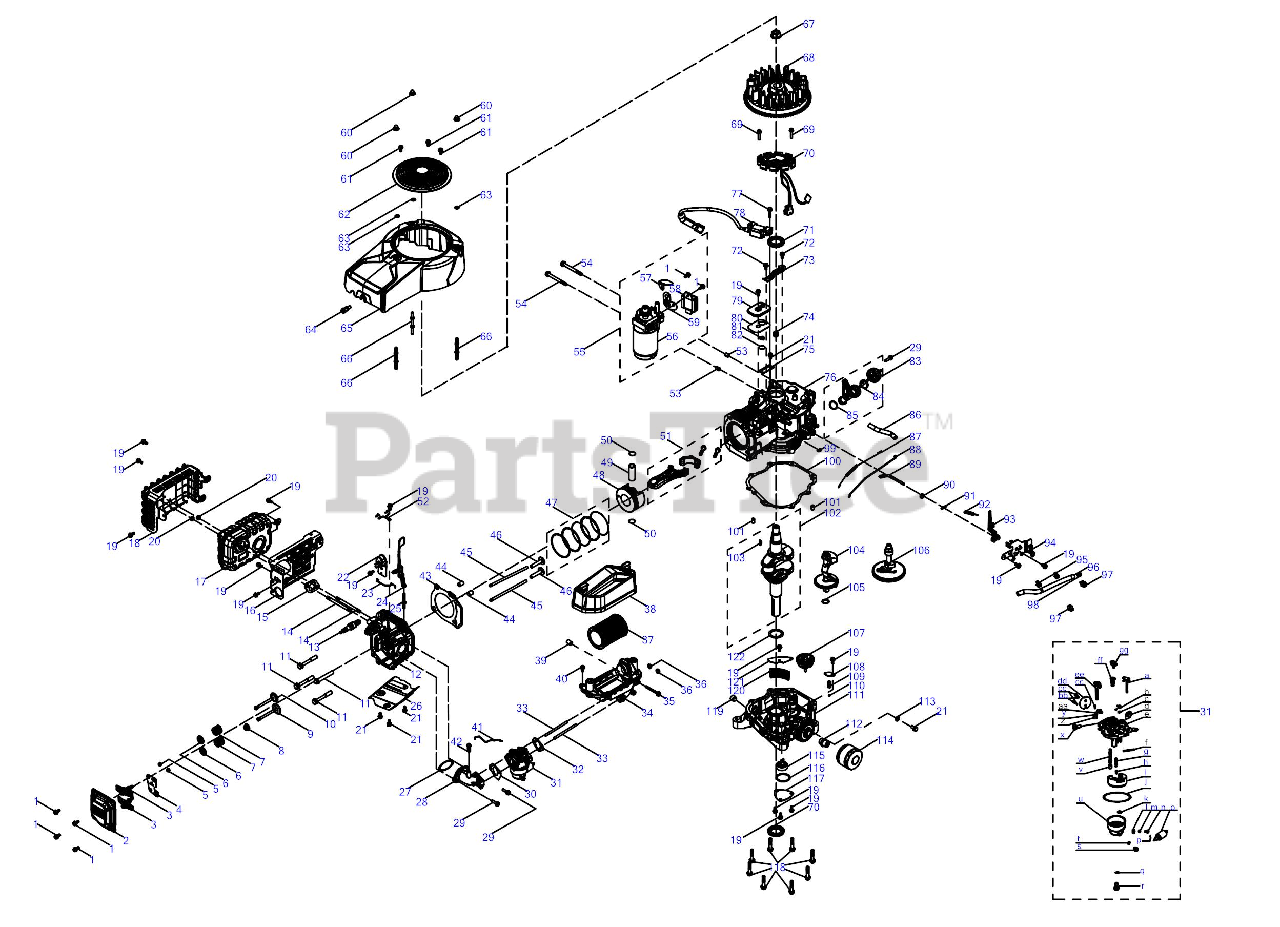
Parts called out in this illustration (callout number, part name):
1	Bolt, M6X16
2	Valve Cover
3	Rocker Arm Assembly
4	Rocker Arm Base
5	Valve Adjust Cap, Exhaust
6	Valve Spring Seat
7	Valve Spring
8	Intake Valve Seal
9	Intake Vavle
10	Exhaust Valve
11	Bolt, M10X1.25X70
12	Cylinder Head
13	Spark Plug
14	Stud, M8X102
15	Gasket, Muffler
18	Muffler Guard
19	Bolt, M6X14
21	Bolt, M6X12
22	Thermal Switch
23	Thermal Lever
24	Shield Assembly
26	Shroud, Down
27	O-Ring,36X2.5
28	Inlet Pipe
29	Bolt, M6X22
30	Gasket, Carburetor
31	Carburetor
32	Gasket, Air Filter
33	Stud, M6X92
34	Air Filter Base Assembly
35	Bolt, M6X55
37	Air Filter Element
38	Air Filter Cover Assembly
39	Bush, 11X6.6X30
40	Bolt, M6X18
41	Choke Lever
42	Self-tappling Screw, ST4.8X16
43	Gasket, Cylinder Head
44	Pin, 12X16
46	Tappet
47	Piston Ring Set
49	Piston Pin
50	Circlip
51	Connecting Rod Assembly
54	Bolt, M8X80
55	Electric Starter
56	Electric Starter
57	Flywheel Outlet Shield
60	Nut, M6
61	Bolt, M5X16
65	Blower Housing
66	Stud, M6X83
67	Nut, M20X1.5
69	Bolt, M5X28
70	Charging Coil
71	Oil Seal, 35X52X7
72	Bolt, M5X10
73	Wire Board
74	Damping Pad
75	Wire Board
77	Bolt, M6X28
78	Ignition Module
79	Breather Cover
80	Gasket, Breather Cover
81	One-way Valve Spring
82	Breather Valve
83	Dipstick Assembly
84	O-Ring, Dipstick
85	O-Ring, Dipstick
86	Breather Hose
87	Idle Spring
88	Throttle Linkage
89	Governor Gear Shaft
90	Oil Seal, 6X11X4
91	Cotter Pin
92	Governor Spring
93	Governor Lever Assembly
94	Governor Gear Bracket Assembly
95	Clamp
96	Fuel Hose, 6.3X12.5X270
97	Clip
100	Gasket, Crankcase
101	Pin,9X14
102	Crankshaft
103	Woodruff Key
104	Balance Shaft
105	Washer, 17.2X1X26
107	Governor Gear
108	Breather Cover
110	Steel Ball, 8.731
111	Crankcase Cover
112	Connection Pipe
113	Washer,6.2X1.5X13
114	Oil Filter
116	Gasket, Oil Pump
117	Oil Pump Cover
118	Bolt, M8X40
119	Earth Bolt
120	Breather Filter Screen
121	Breather Cover
122	Washer, 35.4X1X52
